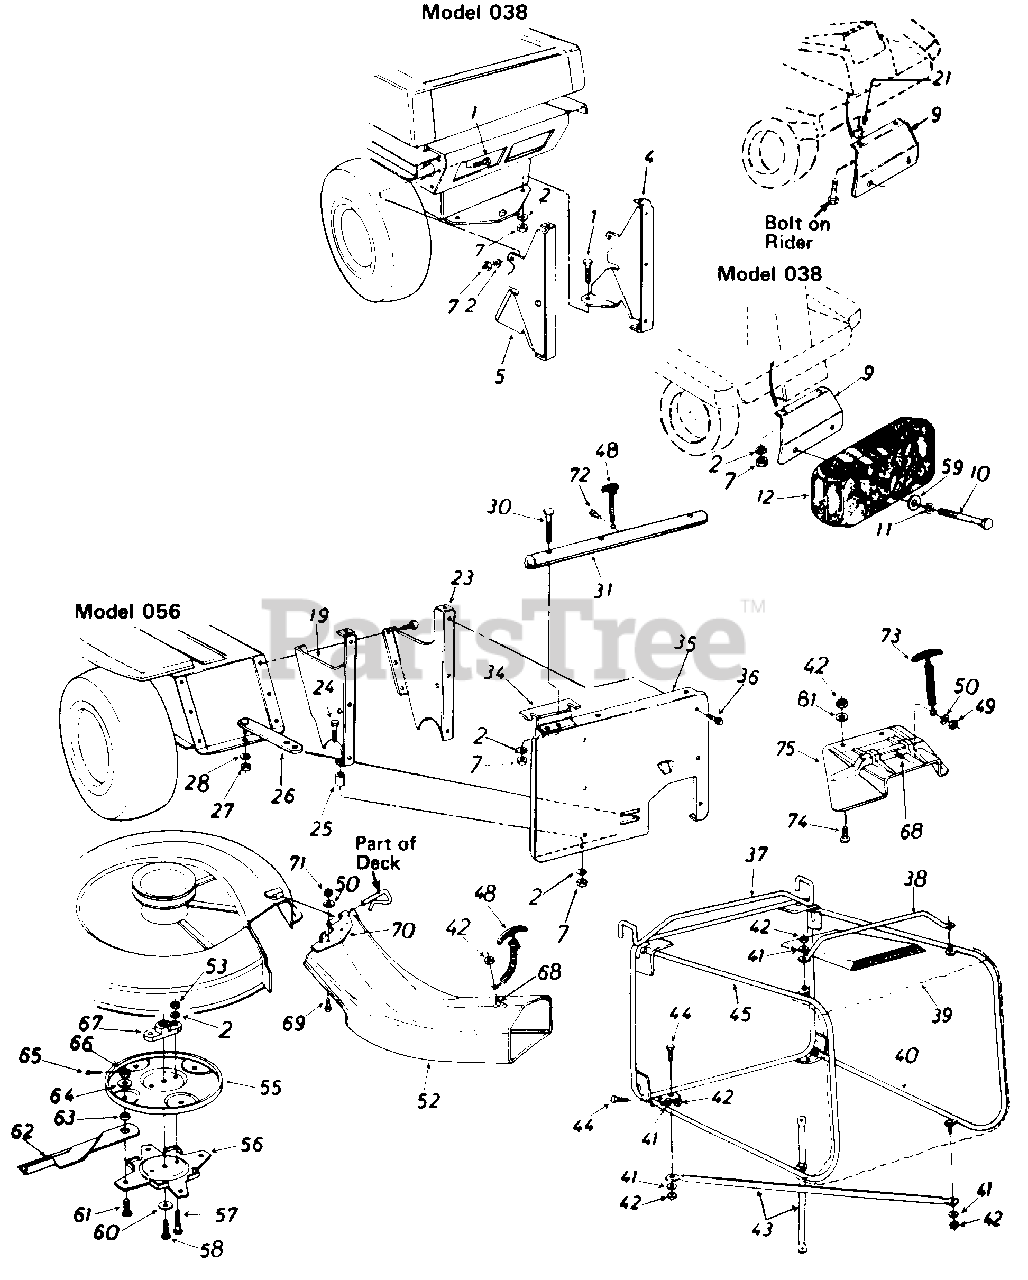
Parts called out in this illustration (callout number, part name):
1	Hex Bolt 5/16-18 x 1" Lg
2	L-Wash. 5/16" I.D.
4	Catcher Support Brkt.-R.H.
5	Catcher Support Brkt.-L.H.
7	Hex Nut 5/16-18 Thd.
9	Counterweight Support Brkt. Ass'y
10	Hex Bolt 3/8-16 x 4.5" Lg.
11	Bell-Wash. .40" I.D. x .88" O.D.
12	Counterweight 38 Ibs.
19	Catcher Support Brkt.-L.H.
21	Spacer .380" I.D. x 1" O.D. x .32" Lg.
23	Catcher Support Bkrt.-R.H.
24	Hex Bolt 5/16-18 x 1.5" Lg.
25	Spacer.38" I.D. x .47" O.D. x 1 " Lg.
28	L-Wash. 1/2" I.D.
30	Curved Carriage Bolt 5/16-18 x 1.75" Lg.
35	Rear Discharge Panel
36	Hex Wash. Hd. Self-Tap Scr. 1/4-20 x .5" Lg.
37	Grass Catcher Frame Ass'y.
42	Hex L-Nut 1/2-20 Thd.
43	Bottom Cross Brace
44	Hex Bolt 1/4-20 x .62" Lg.
50	L-Wash. 1/4" I.D.
52	R.D. Banana Chute Ass'y.
53	Hex Nut 5/16-24 Thd.
55	Upper Blade Disc
58	Hex Bolt 3/8-24 x 1.0" Lg.
59	Fl-Wash. .39' I.D. x 1.12" O.D.
60	Bell-Wash. .39" I.D. x 1.38"
61	Shld. Bolt .50" Dia. x .36"
62	30" Blade Tip
63	Spacer .505" I.D. x .75" O.D. x 1.25" Lg.
64	Fl-Wash. .5" I.D. x 1.25" O.D.
65	Cotter Pin 3/32" Dia. x 1" Lg.
66	Hex Slotted Nut 1/2-20 Thd.
67	Blade Adapter
68	Hex Bolt 1/4-20 x .5" Lg.
69	Truss Mach. Scr. 1/4-20 x .5" Lg.
72	Hex AB-Tap Scr. 1/4 x .62" Lg.
73	Hook Latch Ass'y.
74	Truss Mach. Scr. 1/4-20 x .50" Lg.
75	R.D. Chute Extension
81	Fl-Wash. .281" I.D. x .50" O.D. x .063
